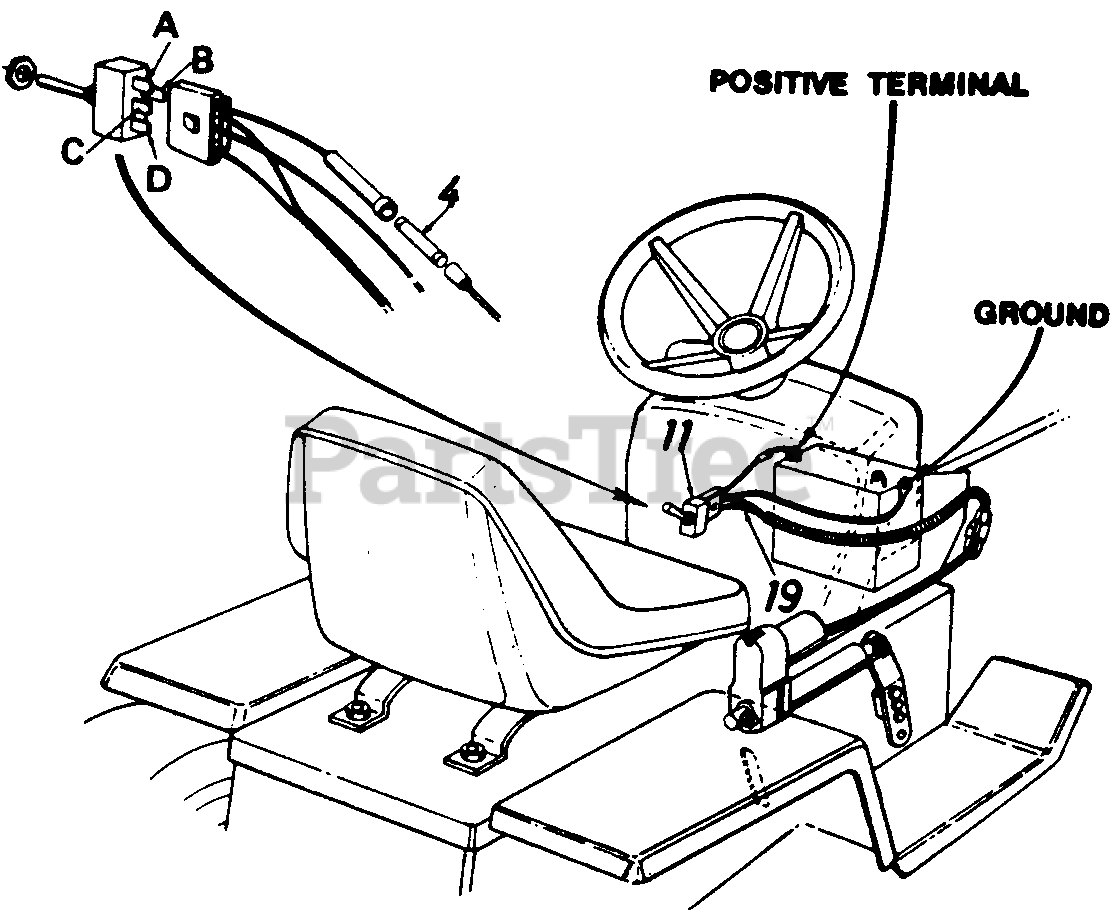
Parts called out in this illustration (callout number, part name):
4	Fuse 30 AMP
11	Toggle Switch
19	Wire Harness
A	Blue Wire-Connects to Positive Terminal on Battery
B	Yellow Wire-Connects to Actuator
C	Black Wire-Ground Wire-to Frame
D	Red Wire-Connects to Actuator
